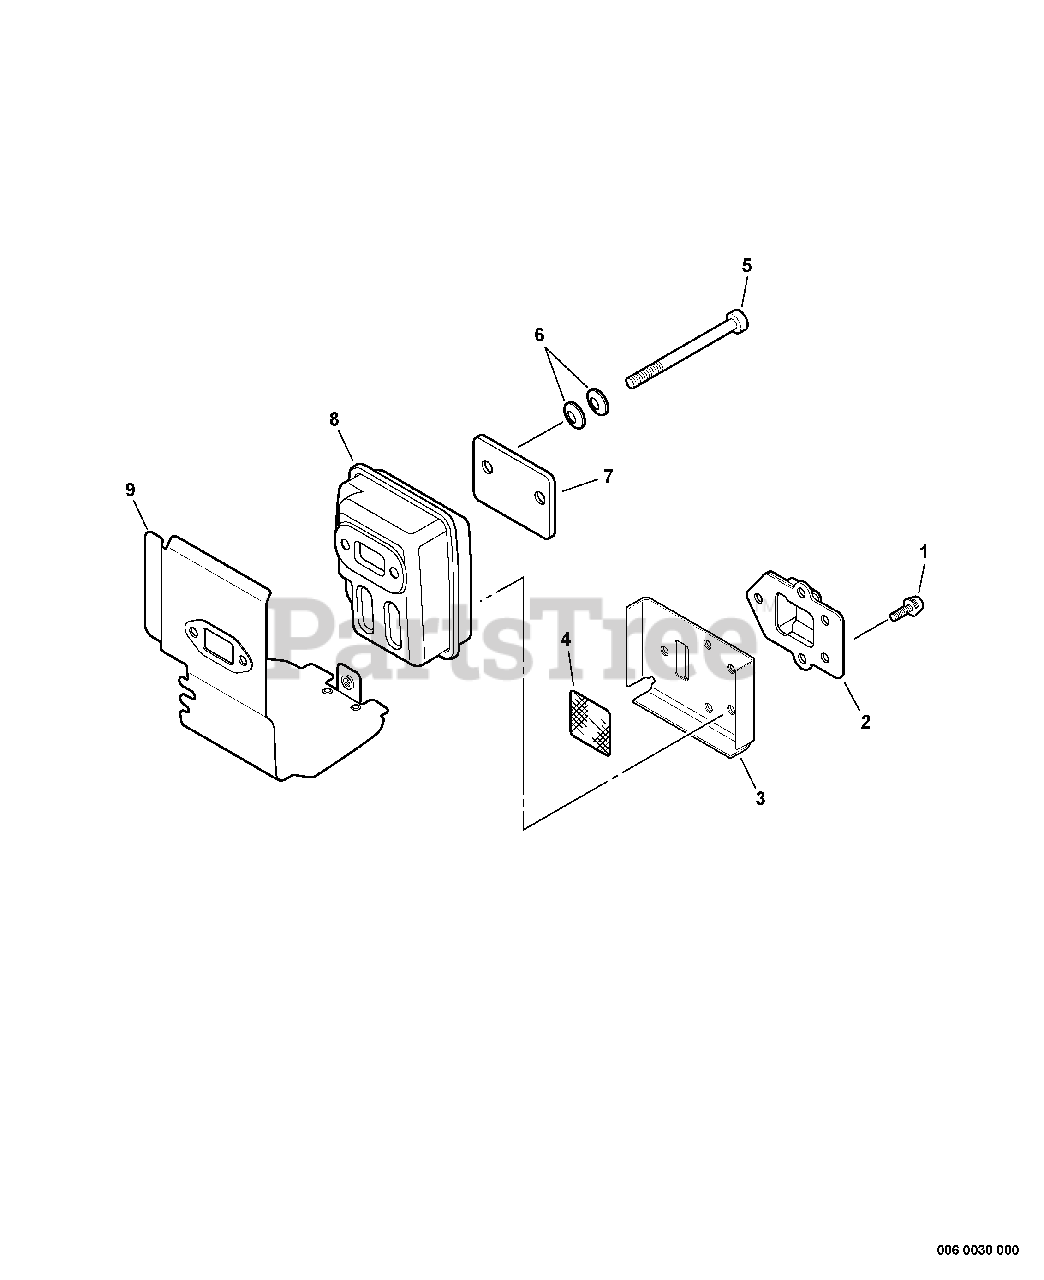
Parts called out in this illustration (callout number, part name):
1	SHIELD, EXHAUST
2	MUFFLER
4	SCREW - 5X55
5	WASHER - CONICAL
6	SCREEN, SPARK ARRESTOR
7	GASKET, EXHAUST
8	GUIDE, EXHAUST
9	SCREW - 4X12
